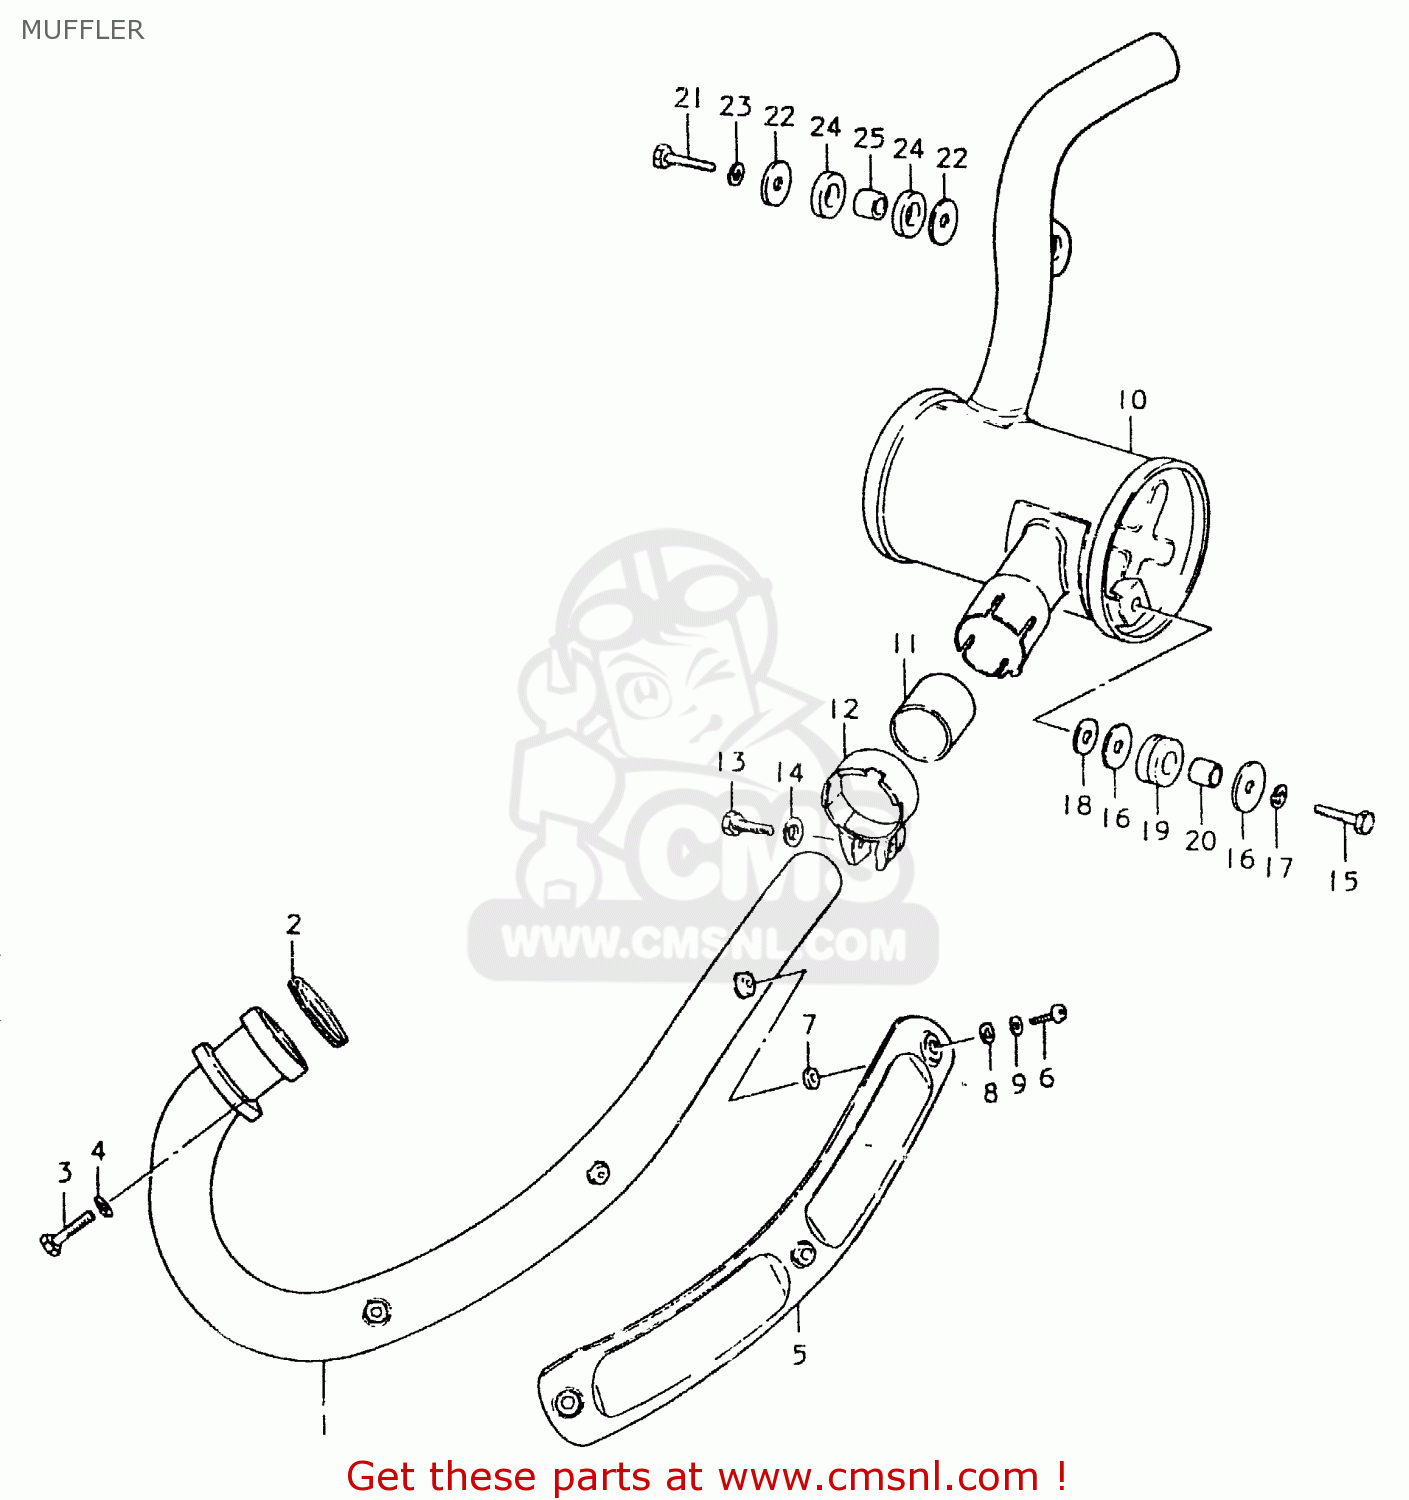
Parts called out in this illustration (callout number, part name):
1	PIPE,EXHAUST
2	GASKET,EXHAUST PIPE (NAS)
3	BOLT (8X30)
4	LOCK WASHER
5	COVER,EXHAUST PIPE
6	SCREW
7	GASKET 6.2X12X1.5 (MCA)
8	WASHER
9	LOCK WASHER
10	BODY,MUFFLER
11	CONNECTOR,MUFFLER
12	CLAMP,MUFFLER CONNECTOR
13	BOLT 8X35
14	WASHER
15	BOLT (8X30)
16	WASHER (8.5X29X1.6)
17	LOCK WASHER
18	GASKET
19	CUSHION
20	SPACER (8.6X13.8X13)
21	BOLT(8X27)
22	WASHER (8.5X29X1.6)
23	LOCK WASHER
24	CUSHION
25	SPACER (8.6X13.8X13)
